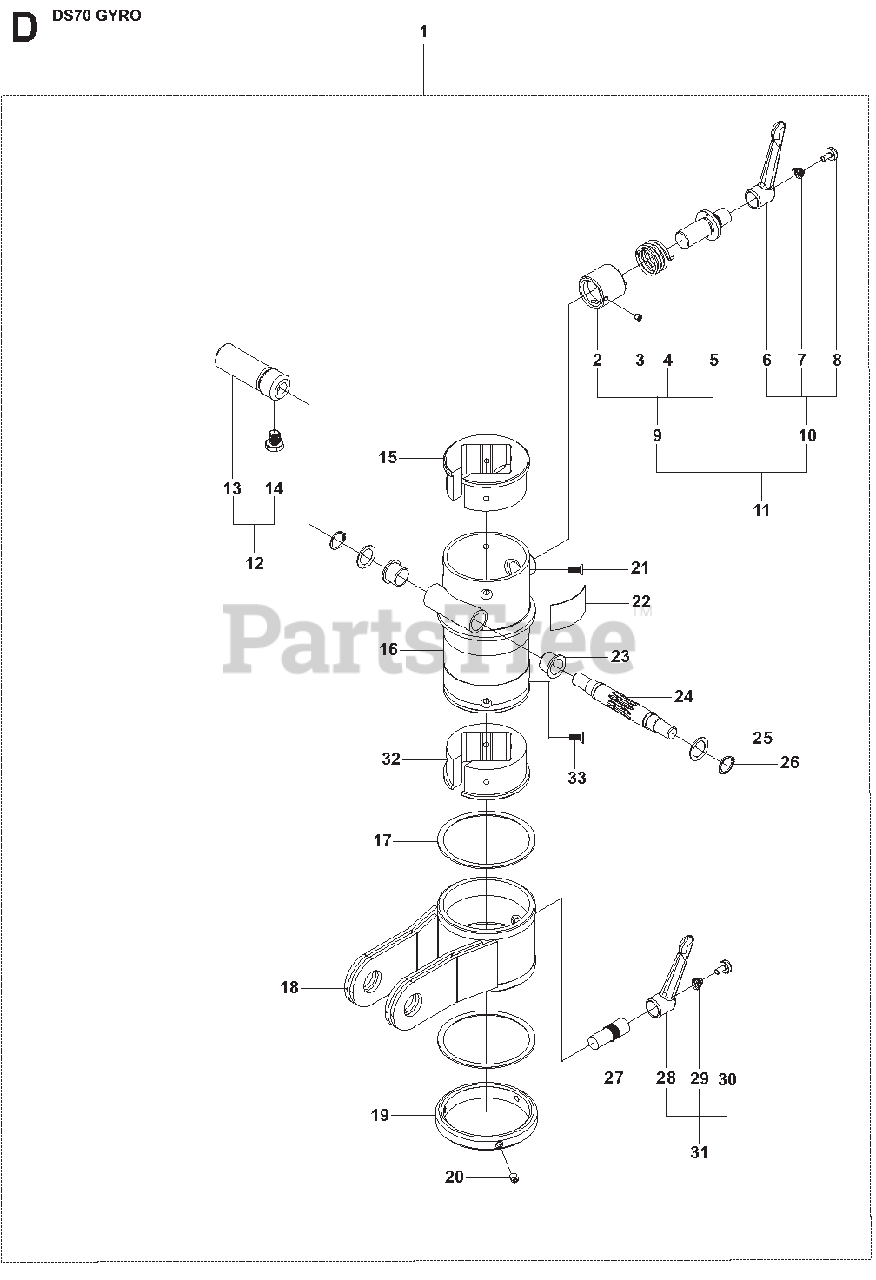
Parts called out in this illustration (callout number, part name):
1	BRACKET GYROIncl. 2-37 and Page E
9	SPRING RETAINERIncl. 2-5
12	FEED HANDLEIncl. 13-14
